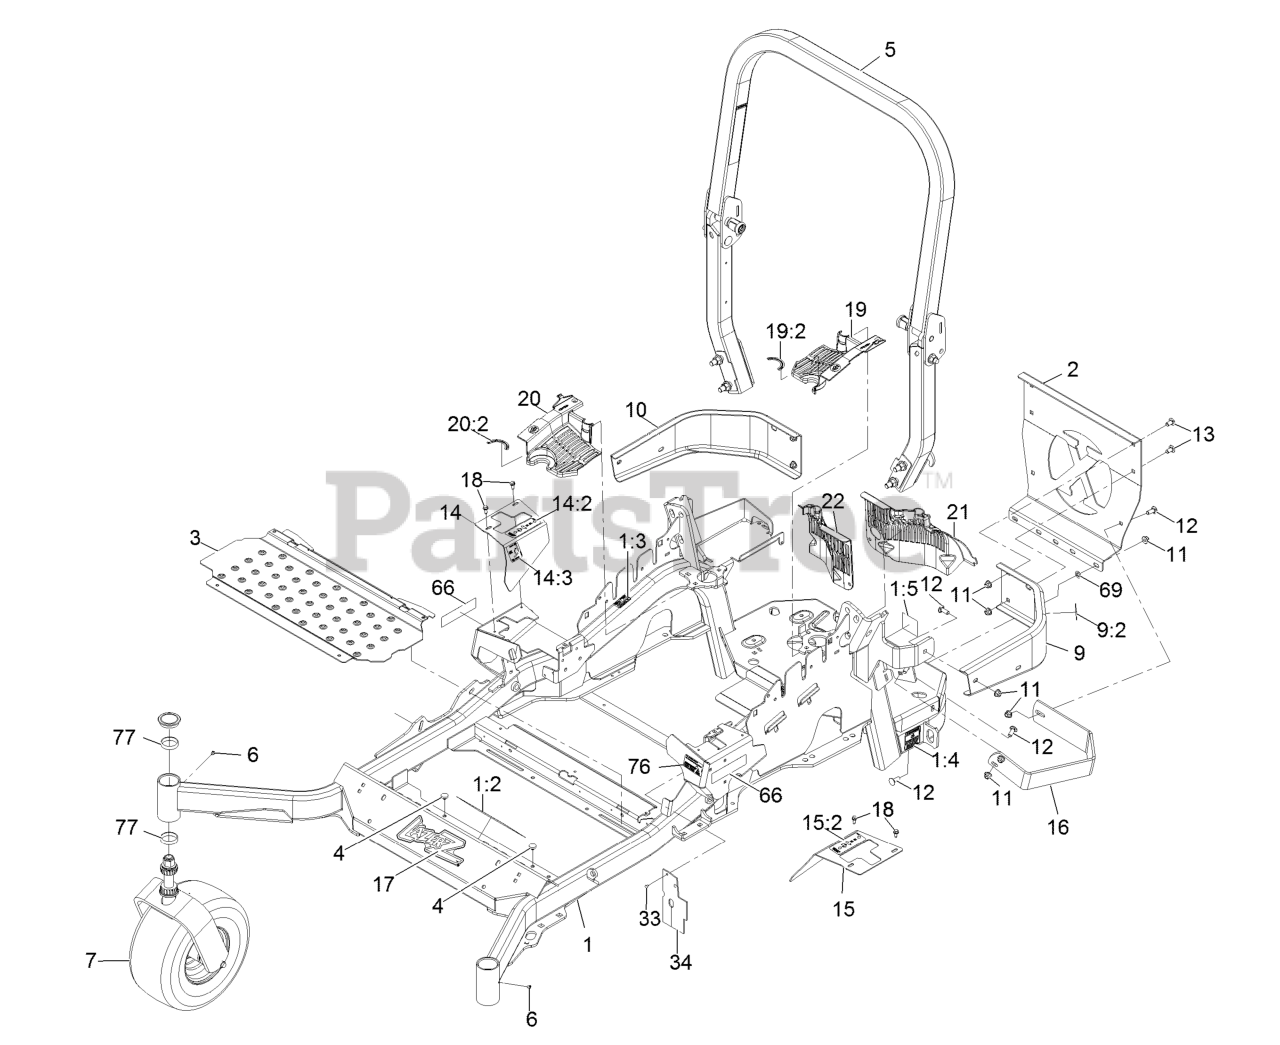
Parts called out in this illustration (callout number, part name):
1	MAINFRAME ASM
1:2	DECAL-SLOPE
1:3	DECAL-CAUTION
1:4	DECAL-BELT DRIVE
1:5	DECAL-SPARK ARRESTER
2	PLATE,REAR GUARD
5	ASM,ROPS SERVICE EXMARK
7	Caster Wheel Asm
9	LH BUMPER ASM
9:2	DECAL-CAUTION
10	BUMPER-RH
11	NUT-HF, NI
12	SCREW-CARR
13	SCREW-CARR
14	RH MOTION CONTROL COVER ASM
14:2	DECAL-MOTION CONTROL
14:3	DECAL-PARK BRAKE
15	LH MOTION CONTROL COVER ASM
15:2	DECAL-MOTION CONTROL
16	GUARD-MUFFLER
17	DECAL,LAZER MODEL
18	SCREW-HWH
19	LH HYDRO GUARD ASM
19:2	DECAL-HYDRO OIL
20	RH HYDRO GUARD ASM
20:2	DECAL-HYDRO OIL
21	GUARD-HYDRO REAR, LH TRIM
22	GUARD-HYDRO, REAR (RH)
33	RIVET-POP
34	DEFLECTOR-AIR FLOW
66	DECAL-X-SERIES
69	NUT-PUSH
76	DECAL-FUEL FILL
77	CUP-BEARING
